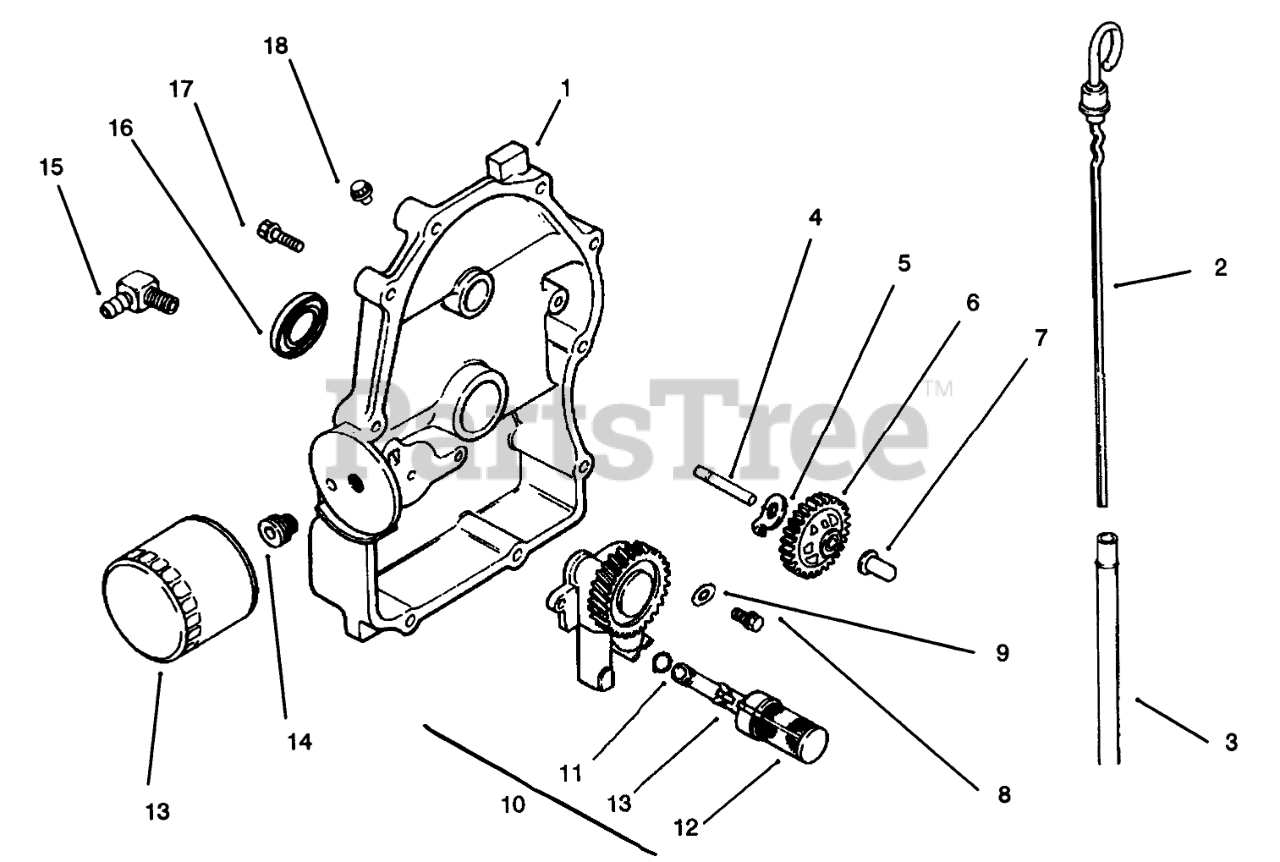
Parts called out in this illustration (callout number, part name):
1	Plate-Closure
2	Dipstick
3	Tube-Dipstick
4	Shaft-Govenor Gear
5	Tab-Locking
6	Governor Gear Assembly
7	Pin-Governor
8	Screw
10	Oil Pump Assembly (Incl. Ref. # 11-12)
11	"O"Ring
12	Pick-up, Oil
13	Filter-Oil
14	Nipple-Oil Filter
15	Connector-90deg.
16	Seal-Oil
18	Switch-Oil Pressure
